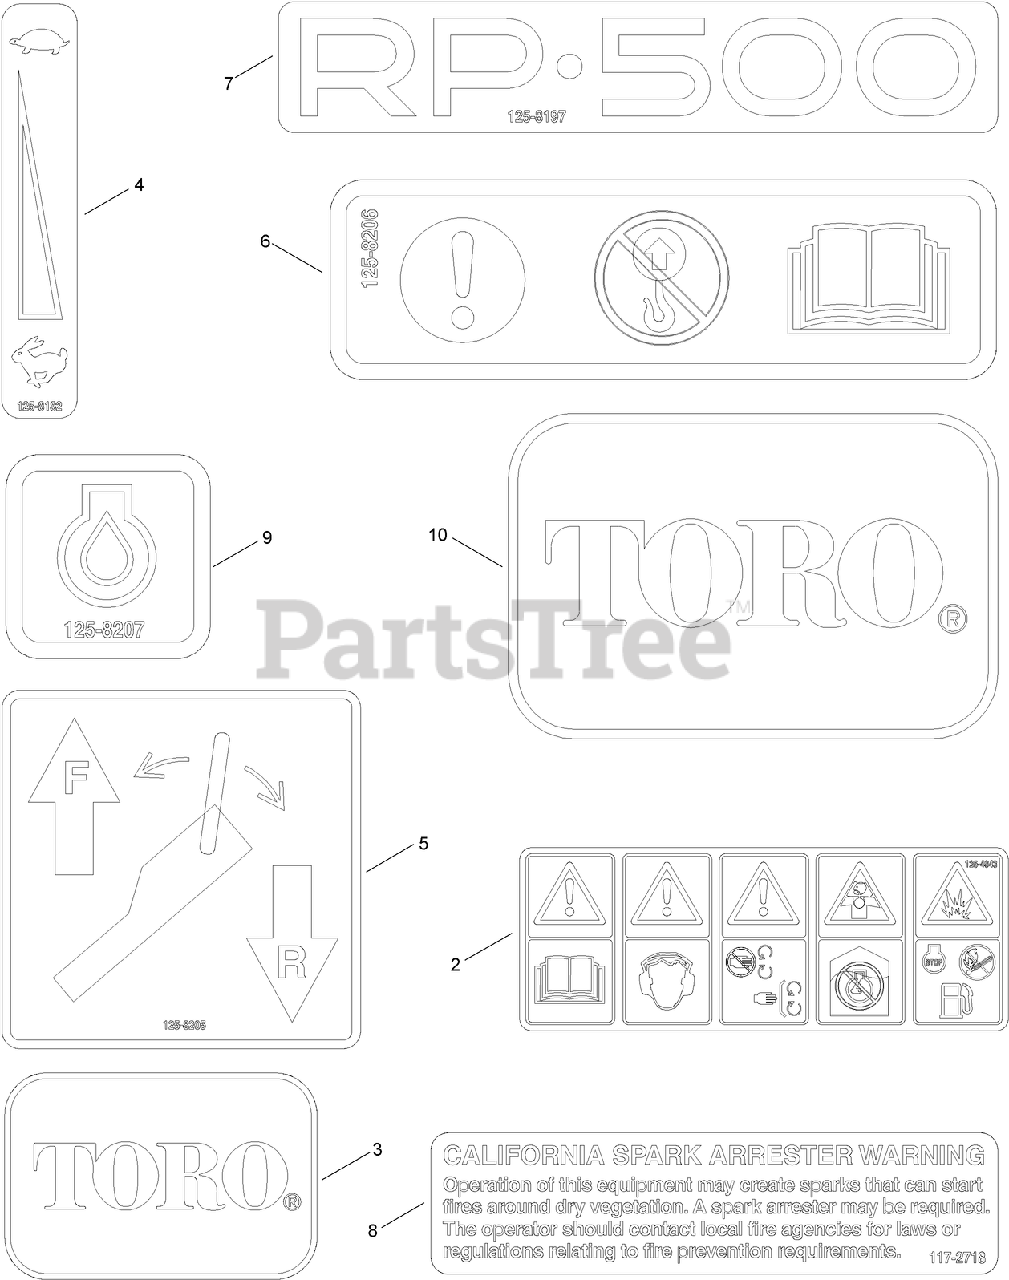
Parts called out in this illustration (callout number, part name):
2	DECAL-WARNING, PLATE
3	DECAL-TORO LOGO
4	DECAL-THROTTLE
5	DECAL-OPERATION
6	DECAL-CAUTION
7	DECAL (RP-500)
8	DECAL-ARRESTER, SPARK
9	DECAL-OIL, ENGINE
10	DECAL
